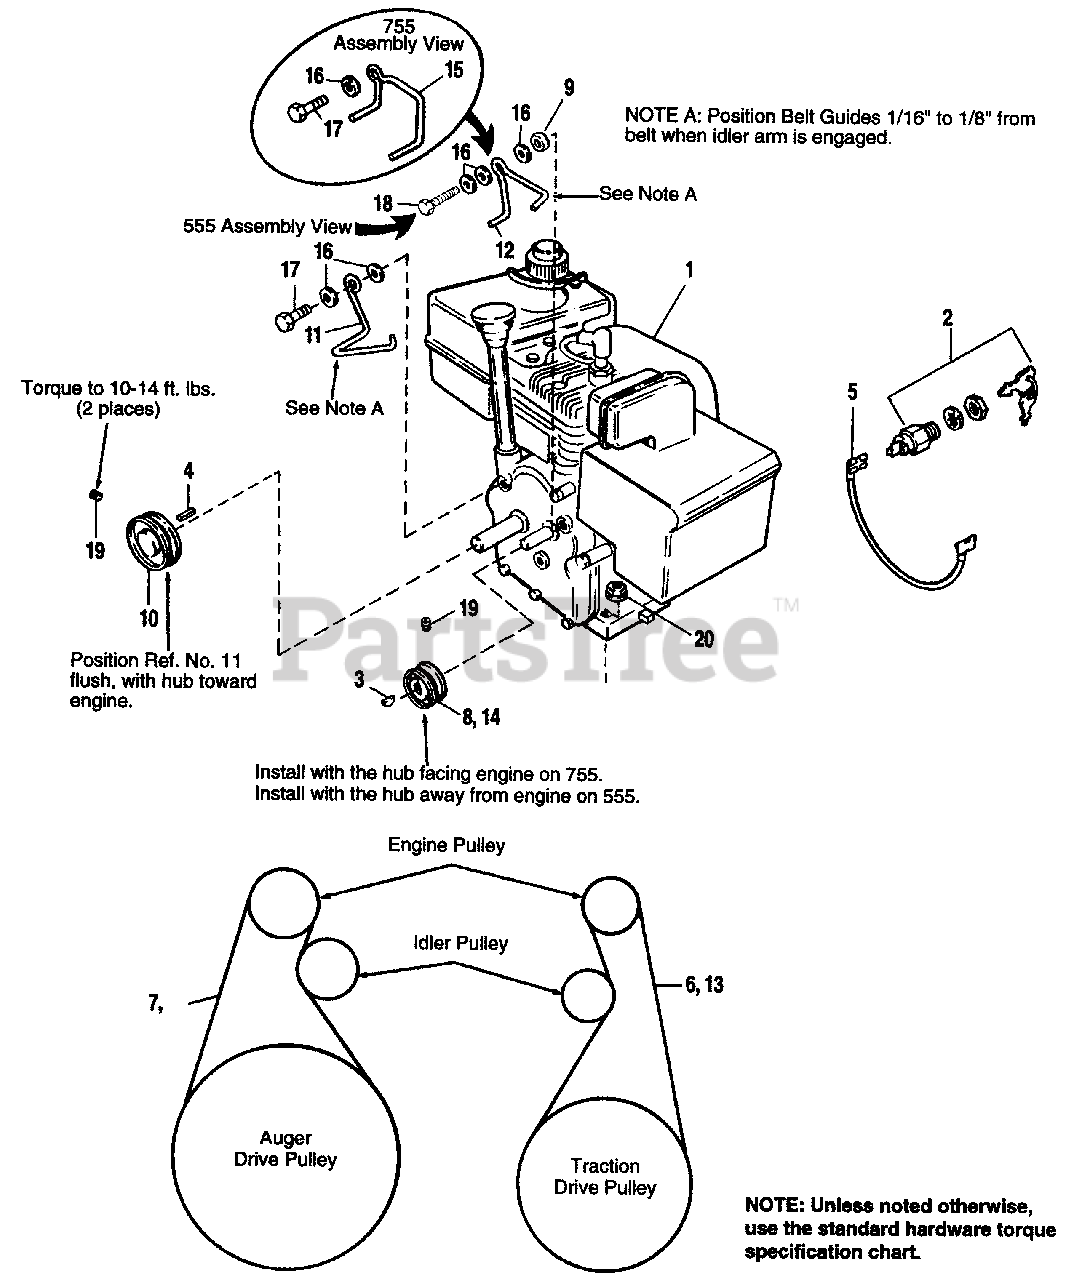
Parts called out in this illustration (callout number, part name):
1	ENGINE, Tecumseh
2	SWITCH ASSY., Ignition w/keys
3	KEY, Woodruff, 1/8 x 5/8
4	KEY, Sq., 3/16 x 3/16 x 1
5	GROUND WIRE
6	BELT, Traction Drive (5 HP only)
7	BELT, Auger Drive
8	PULLEY, Idler (5 HP only)
9	SPACER (5 HP only)
10	PULLEY, Engine
11	GUIDE, Belt
12	GUIDE, Belt (5 HP only)
13	BELT, Traction Drive (7 HP only)
14	PULLEY, Traction Drive (7 HP only)
15	GUIDE, Belt (7 HP Only)
16	WASHER, 5/16 (Qty. 3 used on 5 HP)
17	CAPSCREW, Hex, 5/16-24 x 3/4 (Qty. 1 used on 5 HP)
18	CAPSCREW, Hex Hd., 1/4-20 x 1-3/4
19	SETSCREW, Socket Hd., 5/16-18 x 5/16 (Qty. 1 used on Mfg. No. 1691414)
20	NUT, Hex, Flange Lock, 5/16-18
